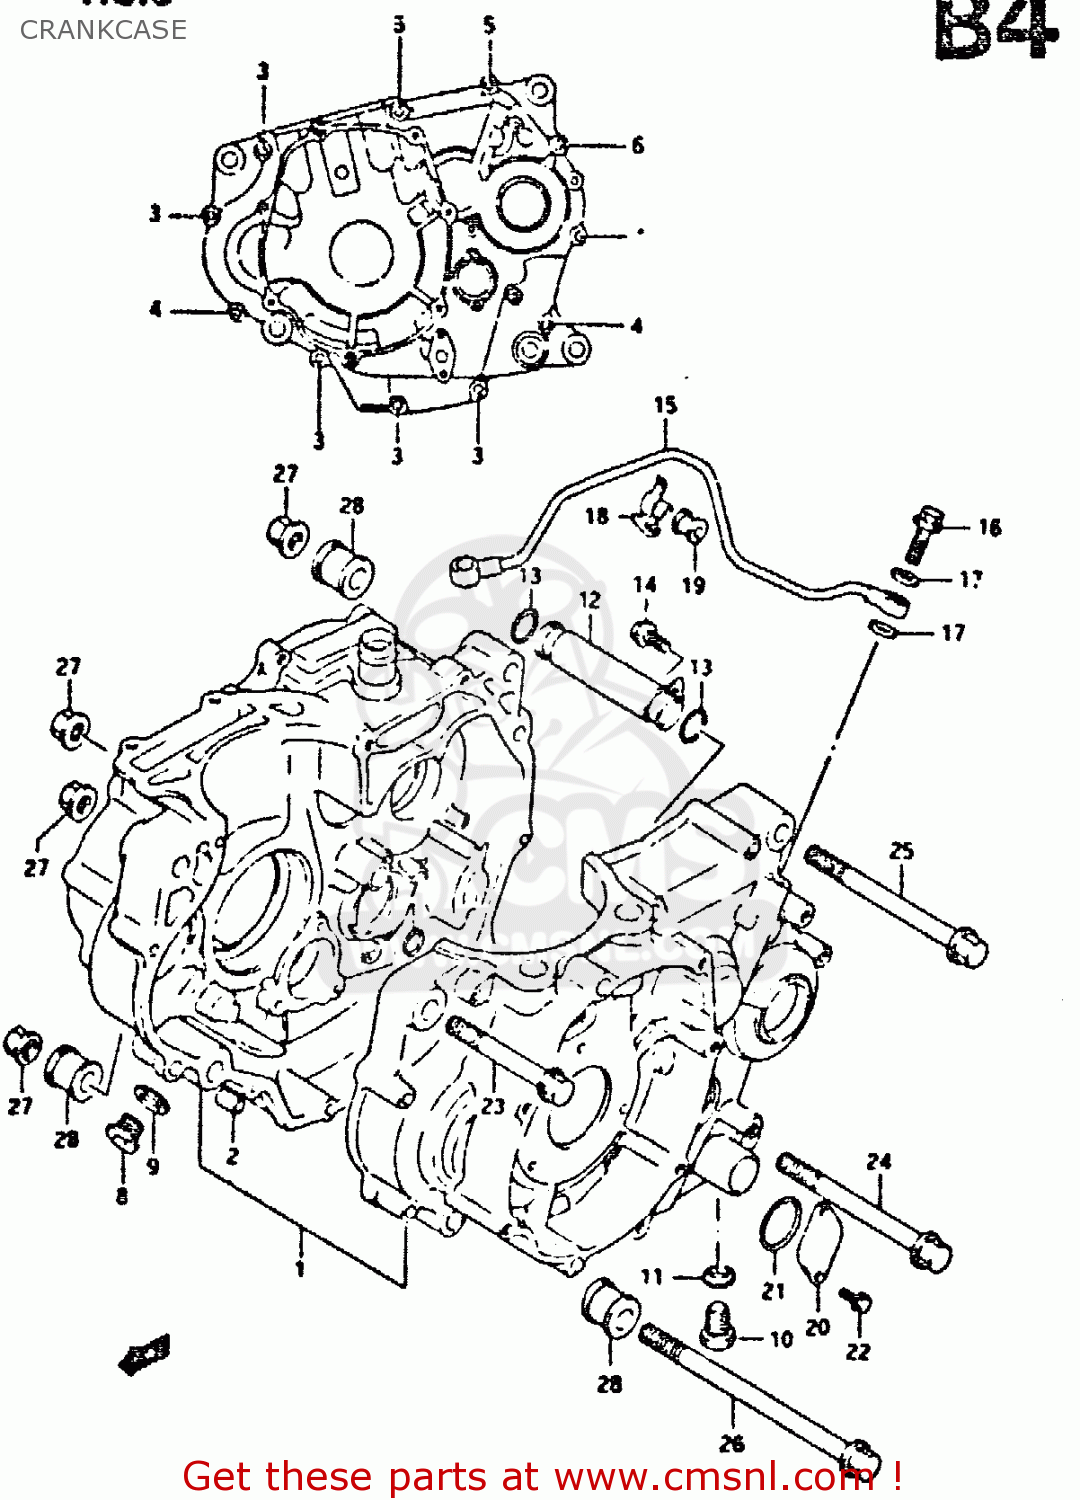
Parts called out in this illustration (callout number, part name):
1	CRANKCASE SET
2	PIN
3	BOLT
4	BOLT
5	BOLT
6	BOLT
7	O-RING
8	PLUG,14X12
9	GASKET(13.8X18.8X4.8) (NAS)
10	BOLT
11	GASKET(12.1X16.2X3.7) (NAS)
12	PIPE,T/M OIL INNER
13	O RING(D:2.4,ID:15.8)
14	BOLT
15	PIPE,T/M OIL OUTER
16	BOLT UNION
17	GASKET 8.2X14X1 (NAS)
18	CLAMP,OIL PIPE
19	CUSHION
20	CAP,NEUTRAL SWITCH HOLE
21	O RING(D:2.4,ID:26.2)
22	BOLT
23	BOLT 10X85
24	BOLT
25	BOLT(10X115)
26	BOLT
27	NUT
28	SPACER,ENGINE MOUNT
